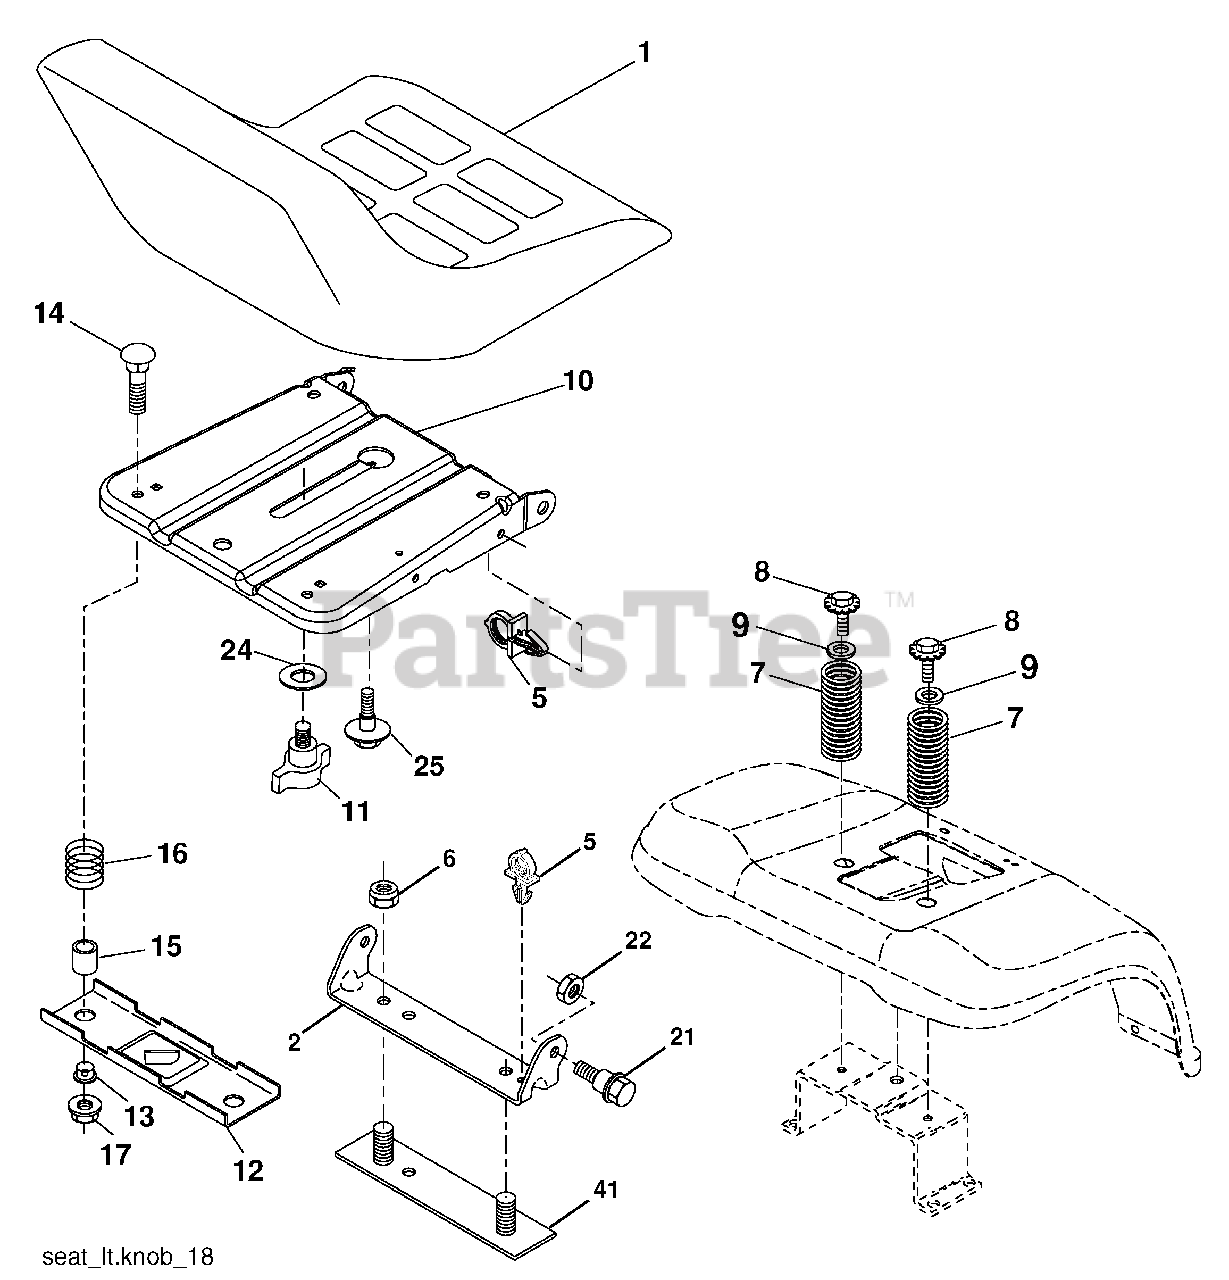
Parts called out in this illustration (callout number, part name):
1	Seat
2	Bracket Seat Pivot
5	Clip Push-In Hinged
6	Nut Lock Hex w/Ins 3/8 - 16
7	Spring Seat Cprsn 2 250 Blk Zi
8	Screw 3/8-16 x 1.5
9	Washer 13/32 x 1 x 14 Ga.
10	Pan Pnt Seat
11	Knob Seat
12	Bracket Pnt Mounting Switch
13	Bushing Snap Blk Nyl
14	Bolt Rdhd Sht Nk 1/4 - 20 x 1 -1/2
15	Spacer Split .28 x .96
16	Spring Cprsn
17	Nut Lock 1/4 Lge Flg
21	Bolt Shoul der 5/16-18 unc-2A
22	Nut Lock Hex w/Ins 5/16 - 18
24	Washer 17/32 x 1-3/16 x 12 Ga.
25	Bolt Shoul der 5/16-18 x .62
41	Strap Asm Fender
